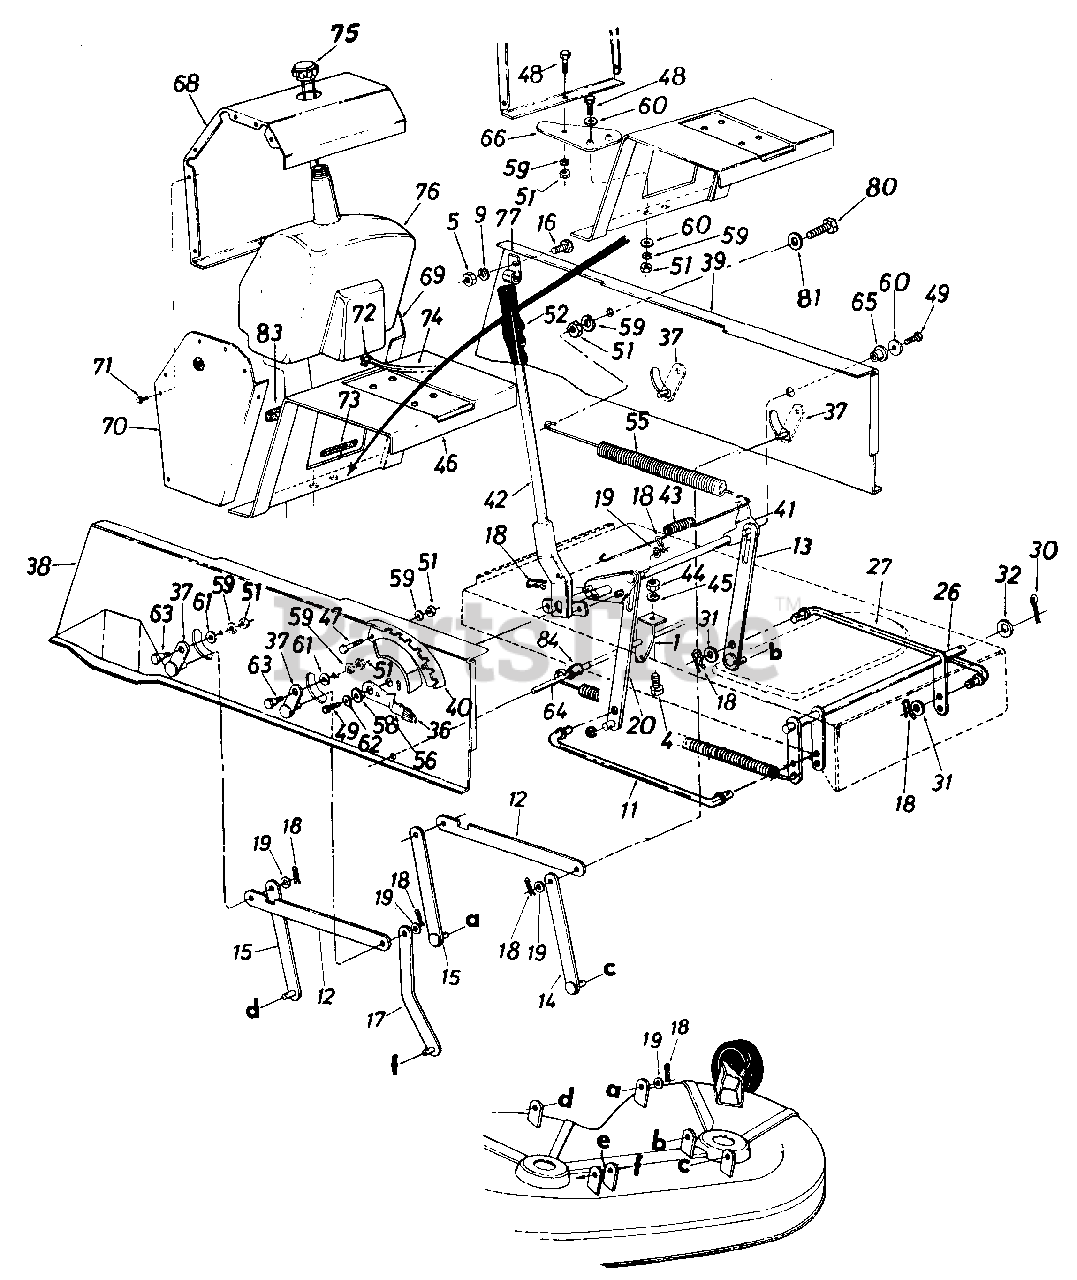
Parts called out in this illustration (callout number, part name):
1	Spring Hanger Bracket
4	Hex Bolt 1/4-20 x .62" Lg.
5	Hex Nut 5/16-18 Thd.
9	L-Wash. 5116" I.D.
11	Stabilizer Rod
12	Connecting Rod 3/16 x 1 x 1 2.5
13	Deck Lift Link Ass'y.
14	Deck Hanger Link Ass'y. Rear L.H.
15	Deck Hanger Link Ass'y.
16	Hex Bolt 5/16-18 x .75" Lg.
17	Deck Hanger Link Ass'y.
18	Inter. Cotter Pin 1/2" Dia.
19	Fl-Wash. .531 I.D. x .93"
20	Deck Lift Link Ass'y.
26	Stabilizer Shaft Ass'y.
27	Stabilizer Rod
30	Cotter Pin 1/8" Dia. x 1.25"
31	Fl-Wash. .385" I.D. x .620" O.D.
32	Fl-Wash. .635" I.D. x 1.12" O.D.
36	Knob Height Adj.
37	Pivot Link Ass'y.
38	Side Panel Upper Frame R. H .
39	Side Panel Upper Frame L. H .
40	Index Brkt.
41	Lift Shaft Ass'y.
42	Lift Handle Brkt. Ass'y.
43	Ext. Spring .56" I.D. x 32 Coils
44	Hex Nut 1/4-20 Thd.
45	L-Wash. 1/4" I.D.
46	Hitch Plate
47	Hex Bolt 5/16-18 x .75" Lg.
49	Hex Wash. TT-Tap Scr. 5/16-18 x .62" Lg.
51	Hex Nut 5/16-18 Thd*
52	Grip
55	Ext. Spring .99" Dia. x 11.00" Lg.
56	Deck Lift Down Stop
58	Flange Brg. .630" I.D.
59	L-Wash. 5/16" I.D.
60	Fl-Wash. .344" I.D. x 1.125" O.D.
61	Fl-Wash. .344" I.D. x .62" O.D. x .063
62	Fl-Wash. .344" I.D. x 1.125" O.D.
63	Shld. Bolt .437" Dia. x .180
64	Running Board Rod
65	Flange Brg. .632" I.D.
68	Gas Tank Housing Main Panel
69	Side Panel L.H. Gas Tank
70	Side Panel R.H. Gas Tank
71	Truss. Mach. B-Tap Scr. #10 x .50" Lg.
72	Hose Clamp .406" Dia.
73	Trim Strip 5" Lg.
74	Gas Line 44" Lg.
75	Gas Tank Cap
80	Hex Bolt 5/16-18 x 1.50" Lg.
81	Fl-Wash. .344" I.D. x .875" O.D.
83	Foam Strip 3/8" x 1-1/8" x 11/2" Lg.
84	Spacer .523" I.D. x .640" O.D. x 1.95" Lg.
